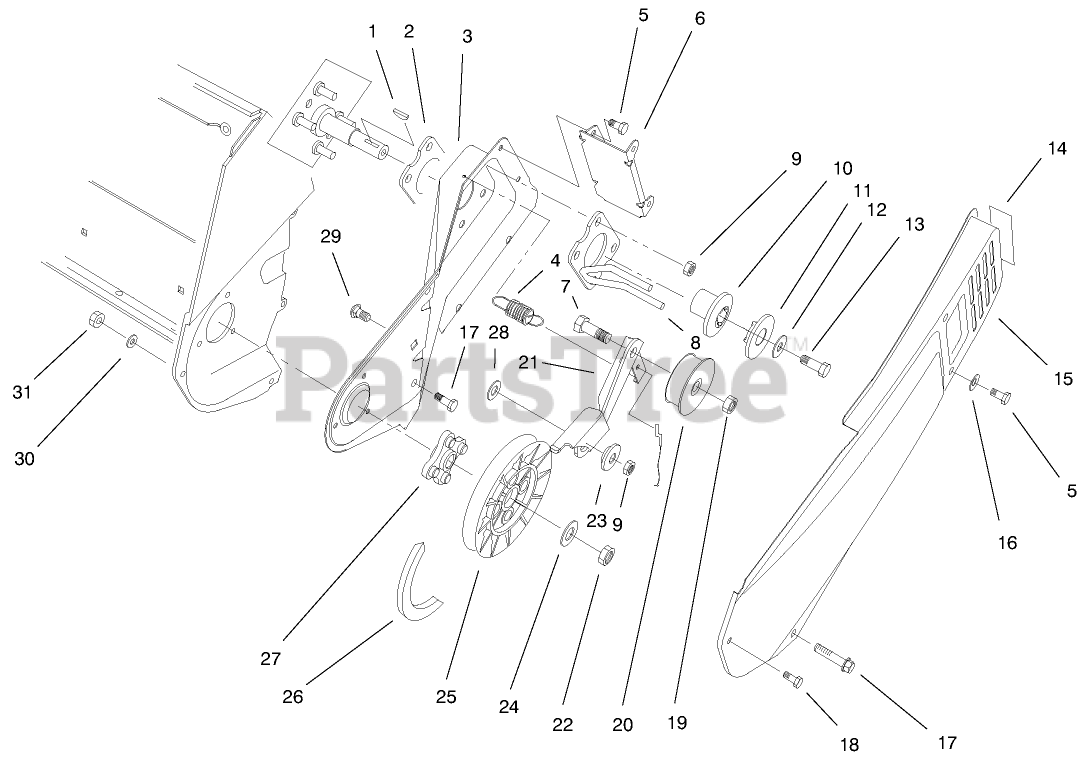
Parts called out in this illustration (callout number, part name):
1	KEY-WOODRUFF
2	PLATE-ENGINE
3	SIDEPLATE-LH
4	SPRING-BRAKE
5	SCREW-HWH
6	BRACKET-COVER, BELT
7	SCREW-HH
8	GUIDE-BELT
9	NUT-LOCK, NI
10	HUB-HALF SHEAVE
11	CAP-HALF SHEAVE
12	WASHER-FLAT
13	SCREW-HH
14	DECAL-HOT
15	COVER-BELT
16	WASHER-FLAT
17	SCREW-PLASTIC
20	PULLEY-IDLER
21	ARM-BRAKE
22	NUT-LOCK, NI
23	BUSHING-IDLER
24	WASHER-FLAT
25	PULLEY-DRIVEN
26	V BELT
28	WASHER
29	SCREW-CARR
30	WASHER-FLAT
31	NUT-LOCK, NI
